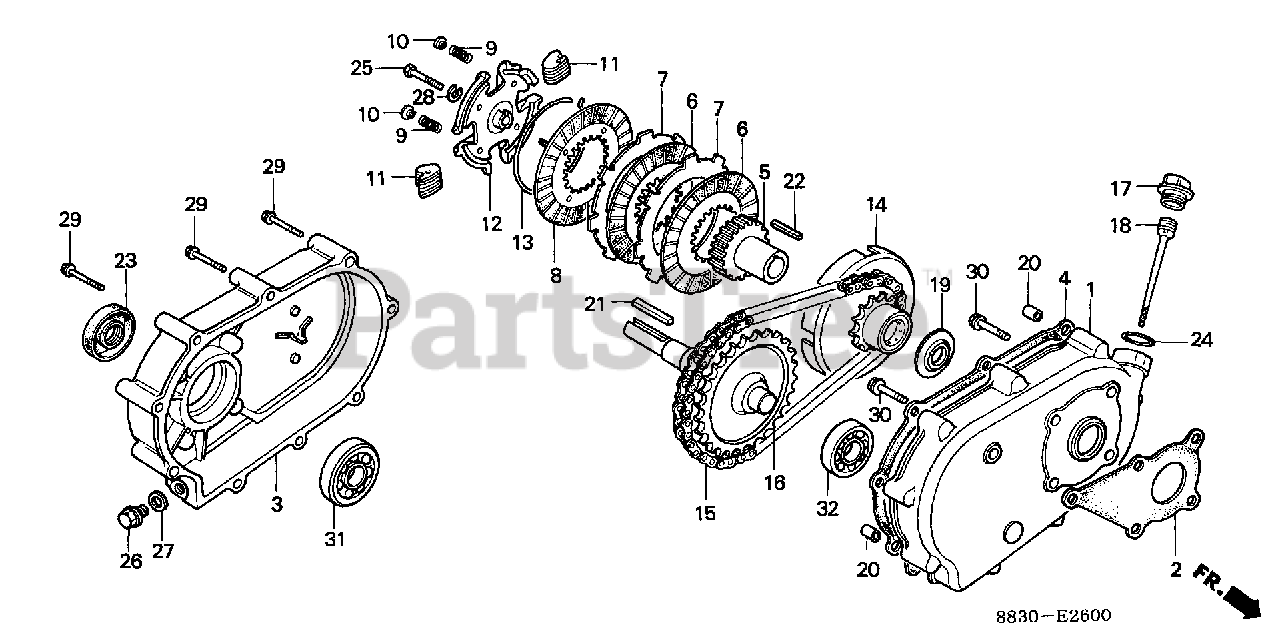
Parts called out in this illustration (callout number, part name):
1	CASE, REDUCTION
2	GASKET, REDUCTION CASE
3	COVER, REDUCTION
4	GASKET, REDUCTION
5	CENTER, CLUTCH
6	DISK, CLUTCH FRICTION
7	PLATE, CLUTCH
8	PLATE, CLUTCH PRESSURE
9	SPRING, CLUTCH FREE
10	HOLDER, CLUTCH SPRING
11	WEIGHT, CLUTCH
12	HOLDER, CLUTCH WEIGHT
13	CENTER, CLUTCH WEIGHT
14	SPROCKET, DRIVE
15	CHAIN, DRIVE (RK428SH-36LE)
16	SHAFT, P.T.O. (28T)
17	CAP, REDUCTION OIL (GRAY)
18	DIPSTICK, OIL
19	WASHER, THRUST (20MM)
20	PIN, DOWEL (8X10)
21	KEY (7X7X33)
21	KEY (7X7X33) (YELLOW)(O/S)
23	OIL SEAL (PJ30507)
24	O-RING (26X2.7)
25	BOLT, HEX. (8X35)
26	BOLT, DRAIN PLUG (12MM)
27	WASHER, DRAIN PLUG (12MM)
28	WASHER, SPRING (8MM)
29	BOLT, FLANGE (6X55)
30	BOLT, FLANGE (8X20) Use up to Engine SN 1609606.
30	BOLT, FLANGE (8X22) Use from Engine SN 1609607.
31	BEARING, RADIAL BALL (6205)
32	BEARING, RADIAL BALL (6206)
